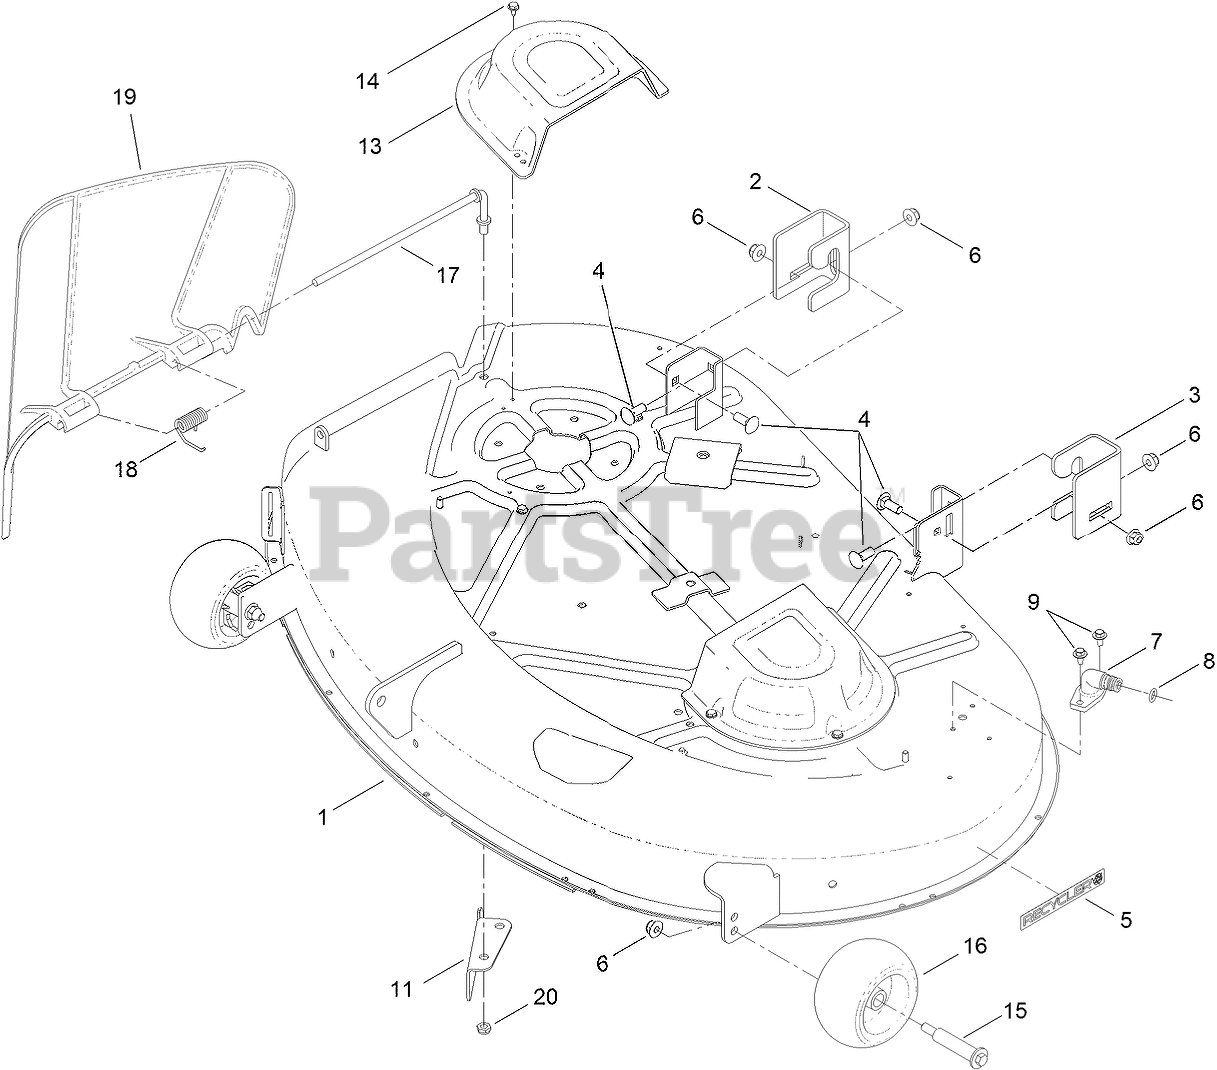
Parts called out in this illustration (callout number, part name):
1	42 INCH DECK AND DECAL ASM
2	BRACKET-HANGER, RH
3	BRACKET-HANGER, LH
4	BOLT-CARR
5	DECAL-RECYCLER
6	NUT-HF, NI
7	FITTING-WASHOUT
8	O-RING
9	SCREW-HHFTF
11	BAFFLE-CUTOFF
13	COVER-BELT
14	SCREW-HWHTF
15	BOLT-SHOULDER
16	ROLLER-SCALP, ANTI
17	ROD-PIVOT
18	SPRING-TORSION
19	DEFLECTOR
20	NUT-LOCK, NI
